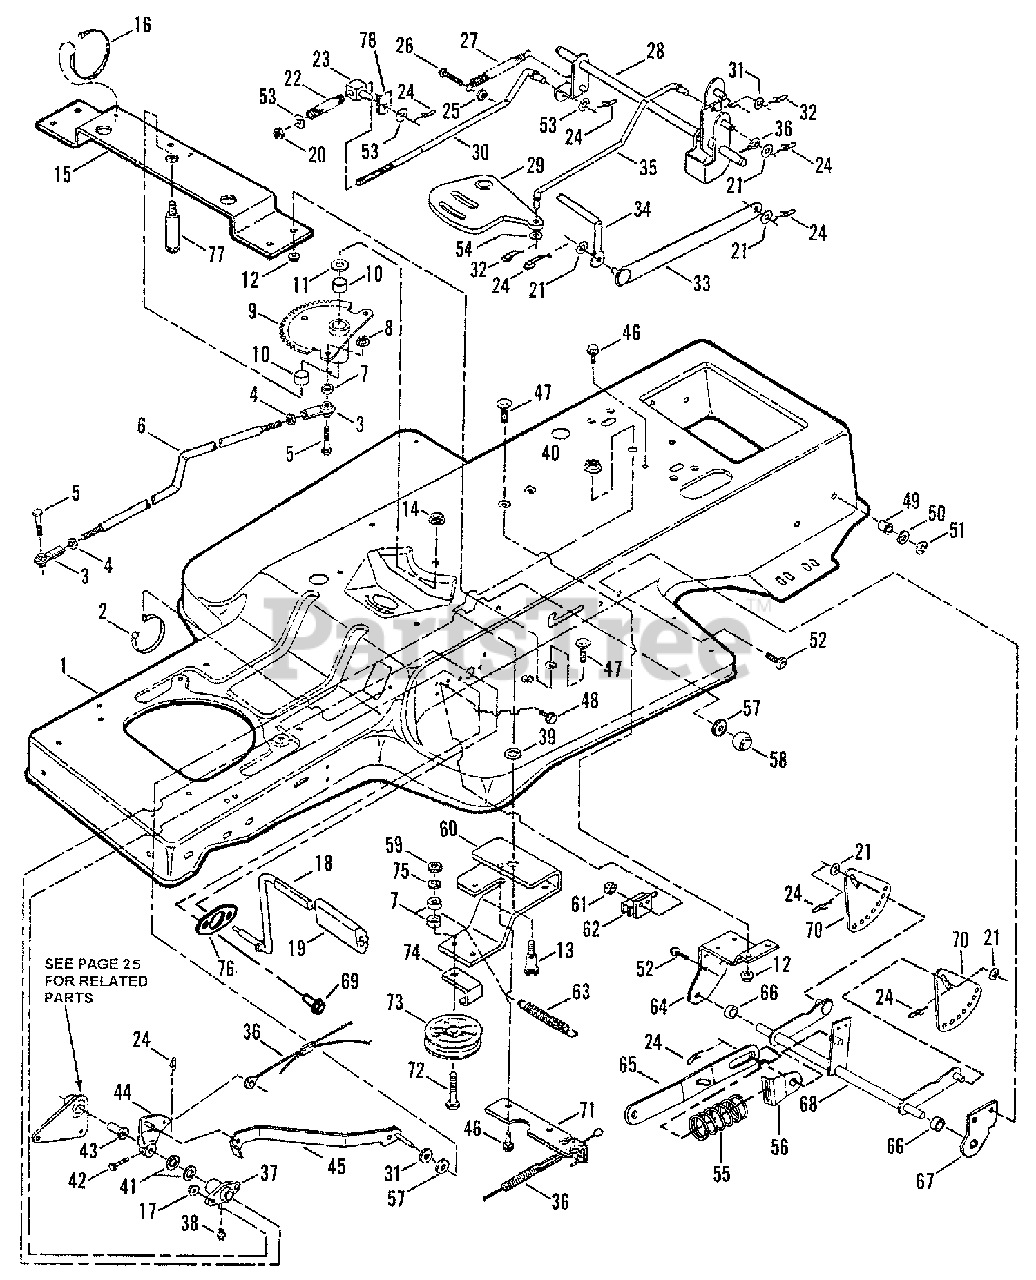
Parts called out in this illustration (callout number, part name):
1	FRAME, Tractor
2	TIE, Wire
3	BALL JOINT, 3/8-24
4	NUT, 3/8-24 Hex Jam
5	SCREW, 3/8-24 x 1-1/4" Hex Head Cap, Grade 2
6	LINK, Drag
7	SPACER, .381 ID, .25" Long
8	NUT, 3/8-16 Hex Flange Lock
9	ASSEMBLY, Sector Gear
10	BEARING, Sector Gear
11	WASHER, 3/4 Thrust
12	NUT, 1/4-20 Hex Flange Lock
13	BOLT, 1/2-13 x 2" Shoulder
14	NUT, 1/2-13 Hex Ctr. Lock, Gr. A
15	BRACE, Sector Gear
16	TIE, Cable 7"
17	NUT, 5/16-18 Hx. Flg. Lk., Gr 5
18	PEDAL, Clutch Brake
19	PAD, Pedal
20	NUT, 3/8-16 Hex Nyloc
21	WASHER, 3/8 Bright Zinc, Flat
22	SPRING, Brake
23	SWIVEL, Inline Brake
24	PIN, 3/8 x 1-7/32" Cotter (Self Locking)
25	NUT, 5/16-18 Hex Center Lock
26	SCREW, 5/16-18 x 1-1/4" Self-Tap
27	SPRING
28	WELDMENT, Brake Arm
29	ARM, Transmission Speed Control
30	ROD, Brake
31	WASHER, 5/16 Flat
32	PIN, 5/16 Cotter, Self-Locking
33	LINK, Shift
34	ASSEMBLY, Shift Lever (Lower)
35	LINK, Speed (Lower)
36	ASSEMBLY, Clutch/Brake Cable
37	ASSEMBLY, Foot Shaft Pivot
38	FITTING, Lube, 3/16
39	WASHER, 1/2 Internal Tooth Lock
40	NUT,1/2-13 Hex Flange Lock
41	WASHER, 5/8 Flat
42	PIN, 3/16 x 1-1/2" Clevis
43	BEARING, Flange
44	ASSEMBLY, Clutch Brake Arm
45	LATCH, Park Brake
46	SCREW, 5/16-18 x 5/8" Self-Tap
47	BOLT, 1/4-20 x 5/8" Carriage
48	SCREW, #10-32 x 5/8" H. W. H.
49	BUSHING, Nylon 1/2
50	WASHER, 1/2 Flat
51	RING, 1/2" External Retaining
52	SCREW, 5/16-18 x 5/8" Truss Head (Torx)
53	WASHER, 3/8" Flat
54	WASHER, 1/16" x 11/32" I.D. x 5/8" O.D.
55	SPRING, 1.03" ID x 3" Long (LT145H38CBV only)
56	GUIDE, Spring (LT145H38CBV only)
57	WASHER, 5/16 Nylon
58	KNOB, Push/Pull (5/16-18 Thd.)
59	NUT, 3/8-16 Hex, Grade B or 5
60	ARM, Idler (Traction Drive)
61	NUT, #10-32 Hex Nyloc
62	SWITCH, DPDT NO/NC
63	SPRING, Traction Drive
64	BRACKET, Rear Lift/PTO Lever
65	LINK, Lift
67	BRACKET, Deck Hang Pivot
68	WELDMENT, Rear Lift
69	SCREW, 5/16-18 x 7/8" Truss Head (Torx)
70	PLATE, Lift Sector
71	EXTENSION, Idler Arm
72	SCREW, 3/8-16 x 2-1/4" Hex Head Cap, Grade 5
73	PULLEY, Flat Idler, 3.47 O.D.
74	GUIDE, Pulley
75	WASHER, 3/8 Yell. Zink, Split Lock
76	WASHER, Pivot- Stiffener
77	SHOULDER BOLT, 3 7/8"x1/2-13
78	BRAKE ARM, TUFF-TORQUE
